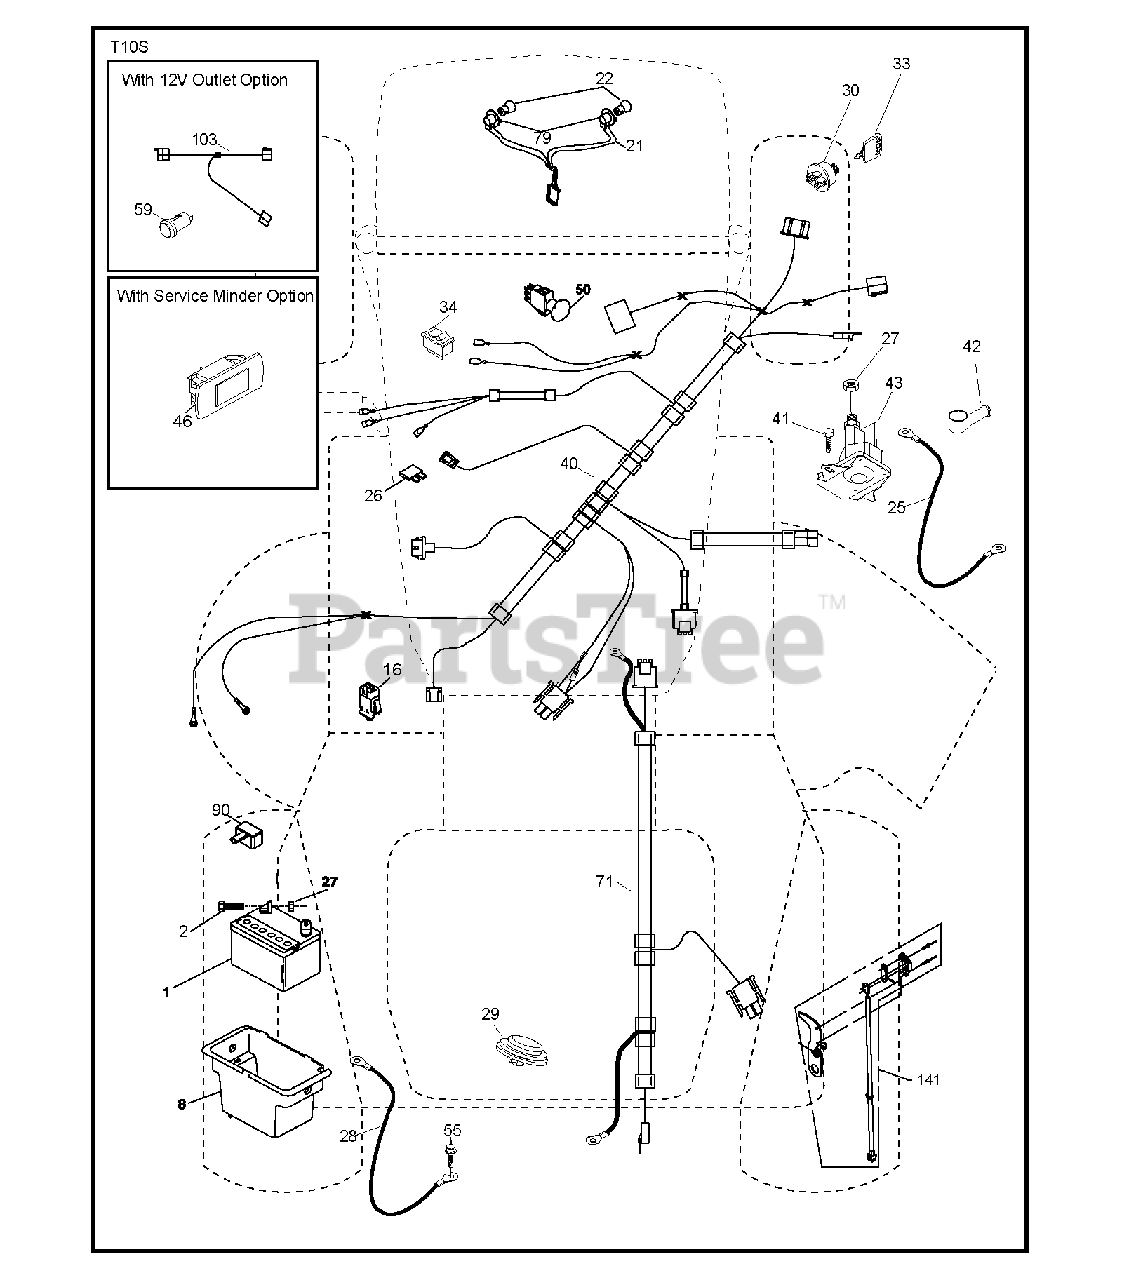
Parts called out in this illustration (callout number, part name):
8	BOX.BATTERY.MNT.REAR.L
16	SWITCH INTERLOOK PUSH-IN
21	HARNESS.LIGHT W/4152J BULBS
22	LIGHTBULB
25	CABLE.STARTER.6GA.BL/RED.14.
26	FUSE 20AMP
27	NUT
28	CABLE.BLACK.18"REAR.BA
29	SWITCH.SEAT.DELTA.OPC.
30	SWITCH.IGN.DELTA.W.LGH.ROS
33	KEY.CHAIN.BLISTER.PACK.GEN.INT
34	SWITCH LT
40	HARNESS.IGN.DASH.HUQ/P
41	SCREW
42	TERMINAL COVER
43	SOLENOID.W/BRASS.PLUNG
46	GUAGE.SRVCMNDR.HRMTR.
50	PTO SWITCH
55	SCREW 5/16"
79	BULB HOLDER ASM.
90	COVER.TERMINAL.BATTERY
141	KIT T2.ROS
